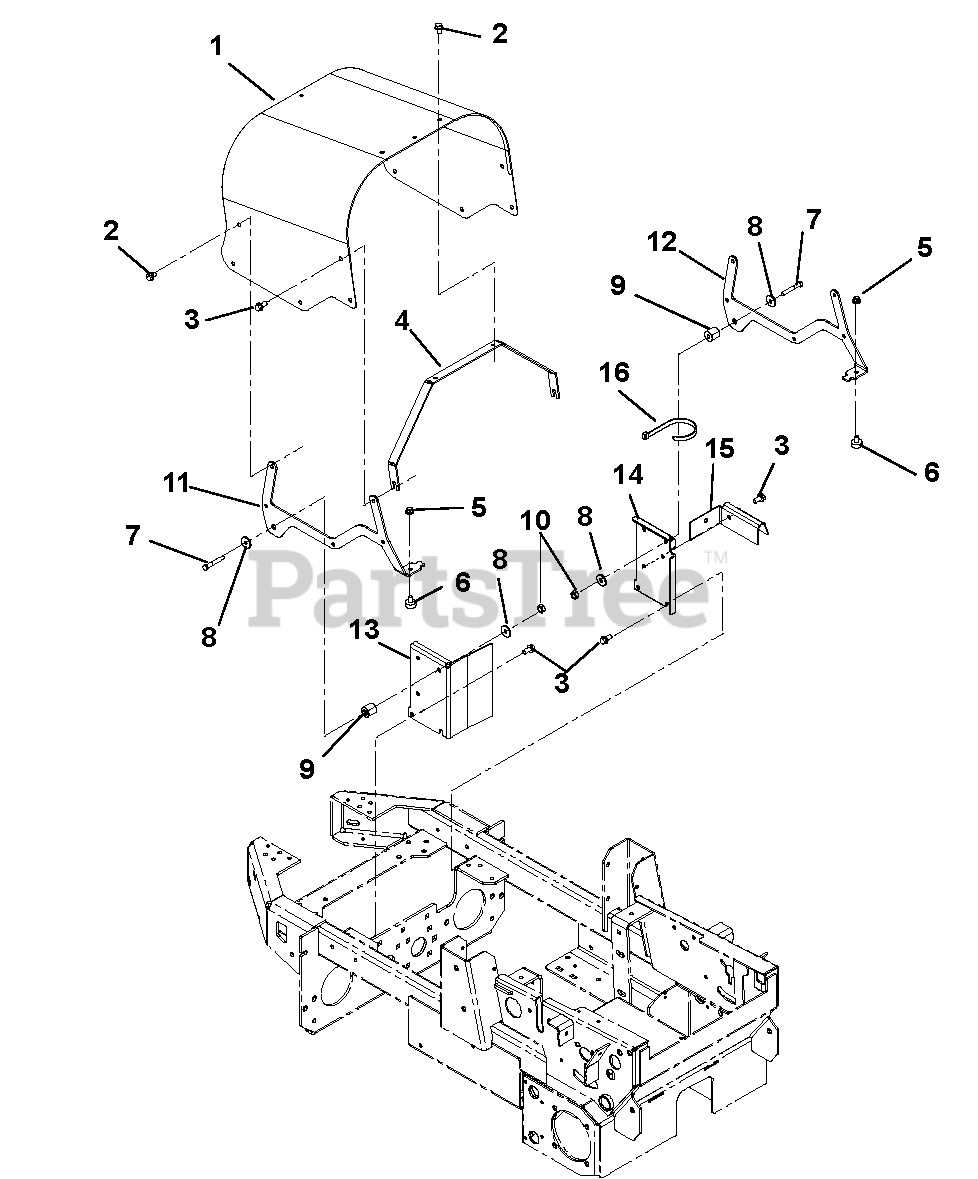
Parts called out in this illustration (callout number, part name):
1	Hood, Outfront Rapid XZ
2	Screw, Tapping .38-16 x .50 Hex Washer Head Thread
3	Screw, Tapping .38-16 x .75 Hex Washer Head Thread
4	Support, Lateral Hood
5	Nut, Spin Lock Flange .312-18
6	Bumper, Rubber
7	Bolt, Hex .31-18 x 2.25 Grade 5
8	Washer, Flat Steel .344 x 1.125 x .135
10	Nut, Locking-Center .31-18
11	Bracket, Hood Left Hand
12	Bracket, Hood Right Hand
13	Bracket, Hood Support #2
14	Bracket, Hood Support #1
15	Cover, Wire
16	Wire Tie (Clutch wire to wire cover)
